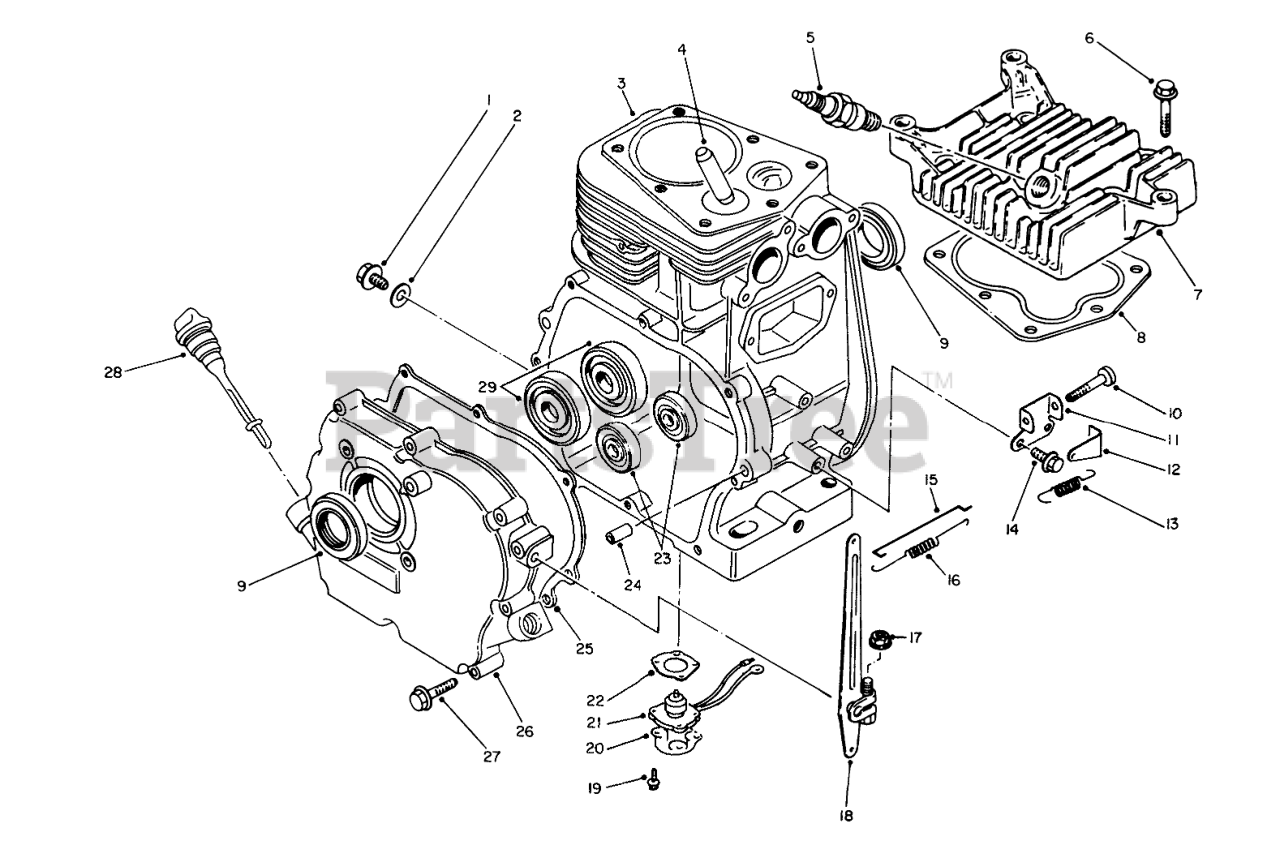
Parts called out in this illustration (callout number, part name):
1	Drain Plug
2	Gasket
3	Cylinder
4	VALVE GUIDE
5	SPARK PLUG
7	Cylinder Head
8	GASKET
9	OIL SEAL
11	Bracket
13	SPRING
15	Rod-Carburetor
16	SPRING
18	CONTROL LEVER
20	Plate
21	SENSOR
22	GASKET
23	Bearing
25	Gasket
26	Cover
28	Gasket
29	Screw
